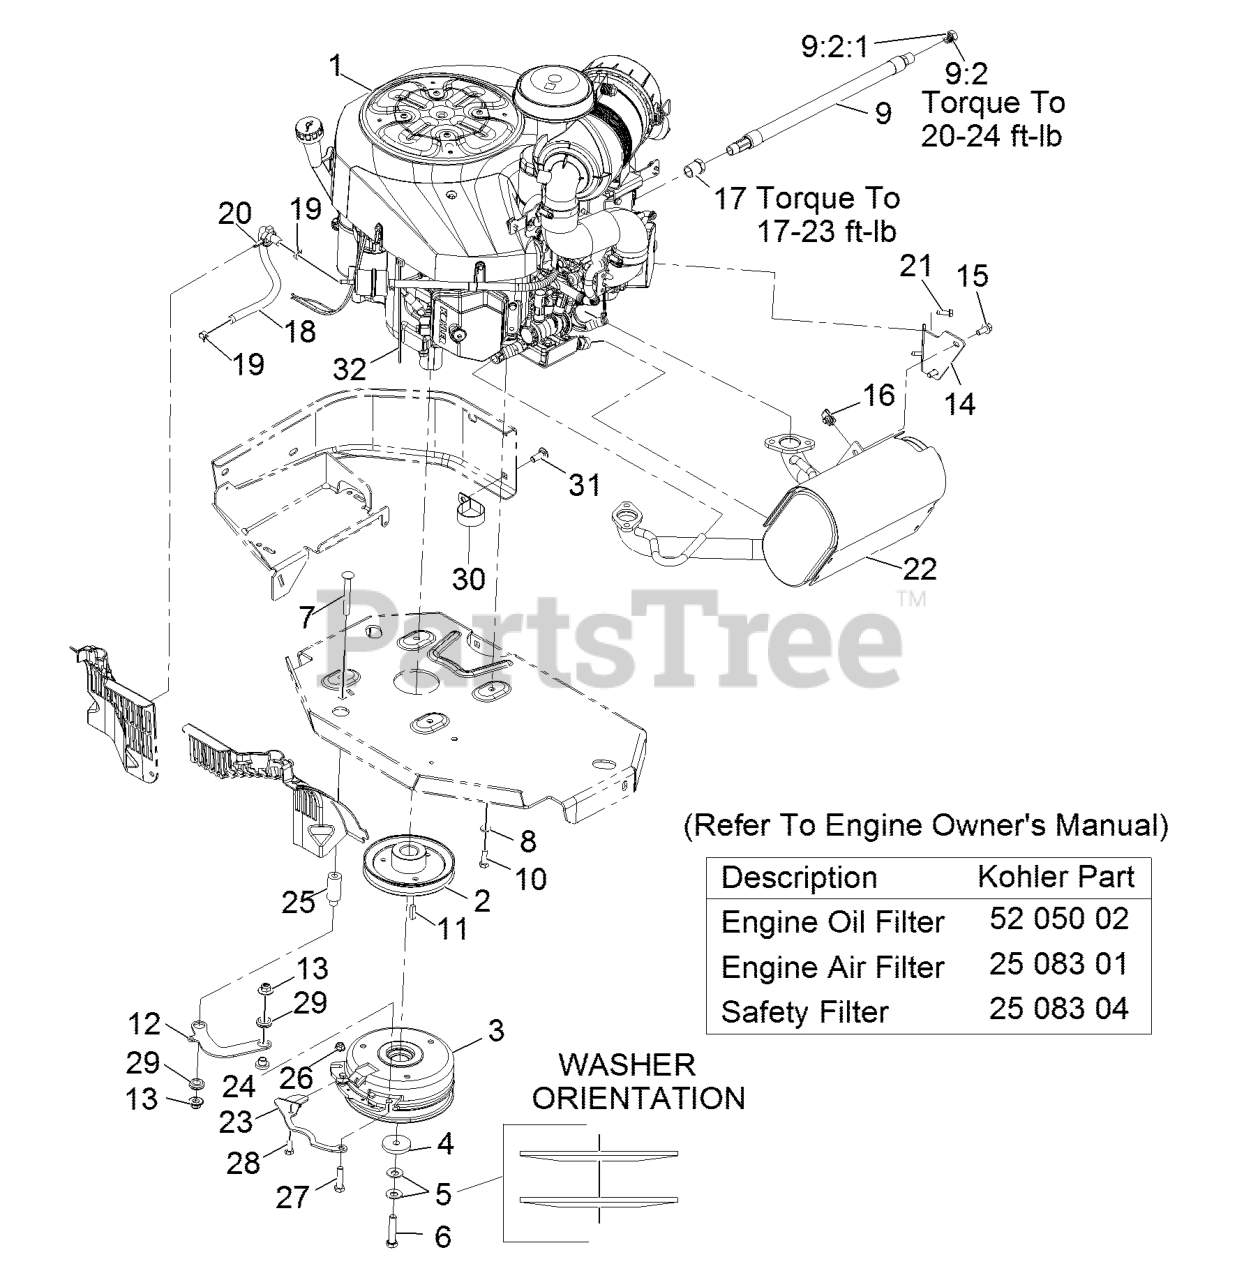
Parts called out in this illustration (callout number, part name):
1	Engine-Kohler
2	SHEAVE
4	WASHER-CLUTCH
5	WASHER-SPRING
6	SCREW-HH W/LOCTITE
7	SCREW-CARR
8	WASHER-SPRING
9	OIL DRAIN HOSE ASM
9:2	PLUG-HH
9:2:1	O-RING
10	SCREW-HH
12	LINK-ANCHOR, CLUTCH
13	Nut-Nyloc 3/8-16 Flg
14	BRACKET-MUFFLER
15	SCREW-HHF
17	BUSHING
19	CLAMP-HOSE
20	CLAMP-HOSE
22	MUFFLER, KC BIG BLOCK AIS
23	BELT-GUIDE
26	NUT-HF, NI
27	SCREW-HH
28	SCREW-HH
29	GROMMET-RUBBER
30	CLAMP-R
31	SCREW-CARR
32	TIE-PLASTIC
